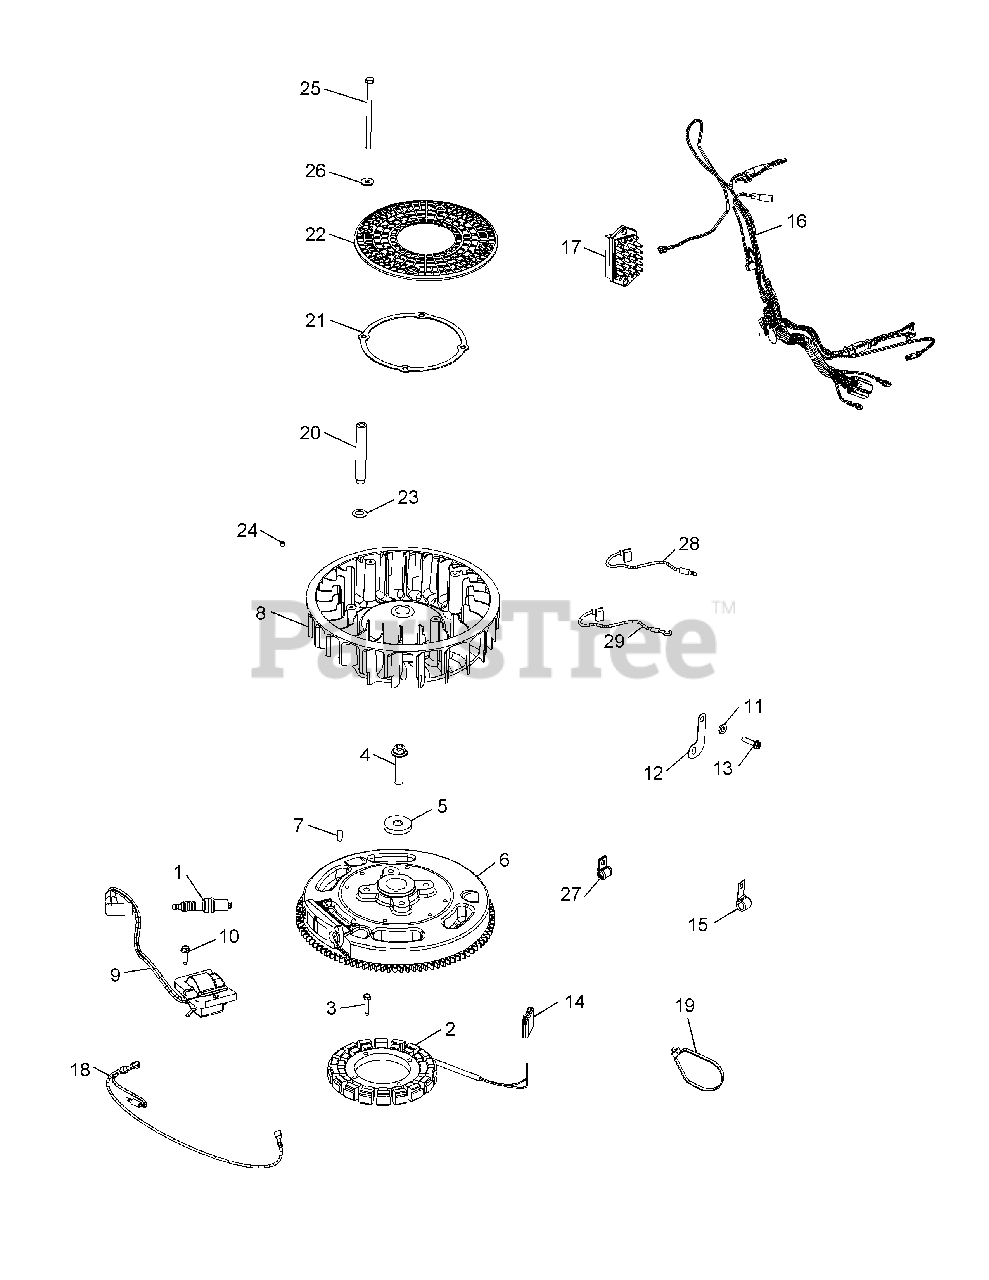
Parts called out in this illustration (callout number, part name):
2	15 Amp Stator Kit
3	Thread Forming Screw
4	Flange Screw, M10 x 1.5 x 45
5	Flat Washer, 13/32"
7	Key, 3/16 x 5/8
9	Ignition Module
10	Thread Forming Screw
11	Flat Washer, 1/4
12	Ground Strap Bracket
13	Hi-Lo Hex Flange Screw
15	Cable Clip
16	Wiring Harness
17	Rectifier Regulator
21	Support Ring
23	Spring Washer, 10 mm
24	Set Screw, #10-24 x 1/4
25	Cap Screw, M6 x 1.0 x 99.5
26	Flat Washer, 1/4
28	Oil Sentry Lead
